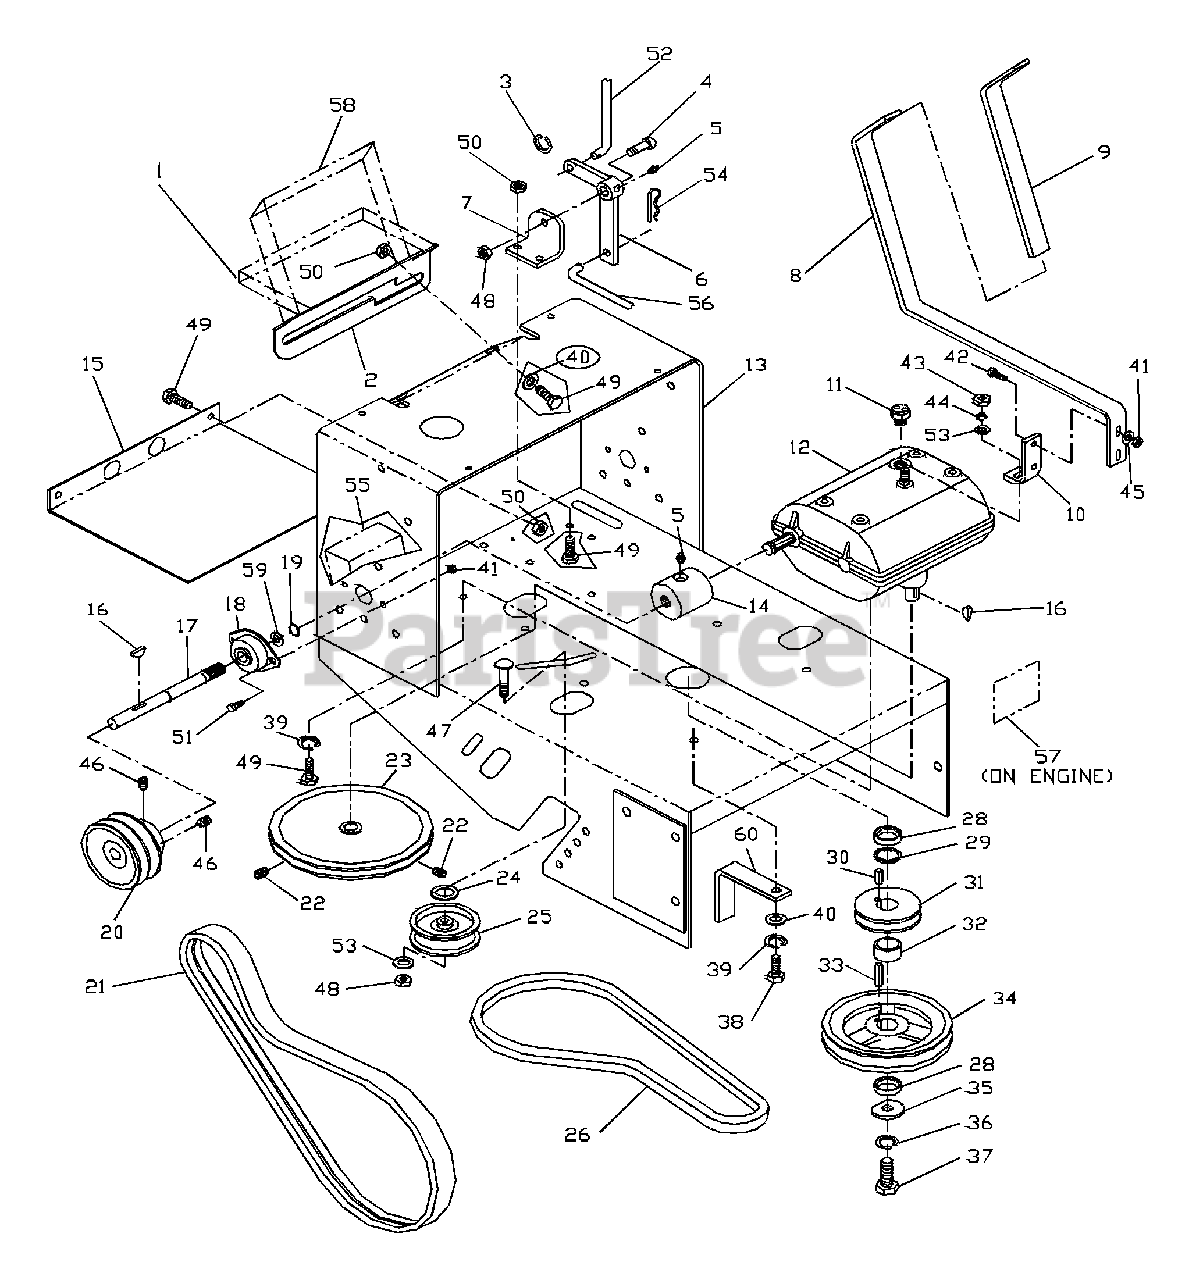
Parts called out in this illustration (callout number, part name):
1	DECAL, SHIFTER
2	SHIFTER PLATE
4	SB 1/2C X 3/4
5	ZERK 1/4-28 STRHT
6	BELL CRANK
8	SHIFTER ARM
9	SHIFTER GRIP
10	SHIFTER BRKT.
11	TRANS. SWITCH
12	TRANSMISSION
13	REAR DECK W/DECALS
15	LOWER BELT SHIELD
16	#9 WOODRUFF KEY
17	DRIVESHAFT
19	RETAINER RING
20	DRIVE PULLEY
21	DRIVE BELT
22	1/4-20 NYLOC SETSCW.
23	INPUT PULLEY
24	1/2 FLAT WASHER STD
25	IDLER PULLEY
26	BELT, TRANSMISSION
27	BELT GUIDE
29	MACH. BUSHING
30	KEY 1/4SQ. X 1/2
33	KEY 1/4SQ. X 1 1/8
34	ENGINE PULLEY
35	CRANKSHAFT WASHER
36	SLW 7/16 STD
37	HCS M10-1.5 X 35MM
37	HCS 7/16F X 1.5 GR 5
38	HTB M8-1.25 X 35MM
38	HCS M8-1.25 X 30MM
39	SLW 5/16 STD
40	5/16 FW STD
42	HCS 1/4C X 1
44	SLW 3/8 STD
45	FW 1/4 STD
46	5/16 NYLOC SETSCW
47	RHSNB 3/8C X 2
48	HLN 3/8C CENTER P.
49	HCS 5/16C X 3/4
51	HCS 1/4C X 5/8
53	FW 3/8 STD
54	#4 HAIRPIN
55	DANGER DECAL
56	BLADE ROD
57	EXHAUST DECAL
58	DECAL, CLUTCH
59	MACH. BUSHING
60	BELT GUIDE, LONG
